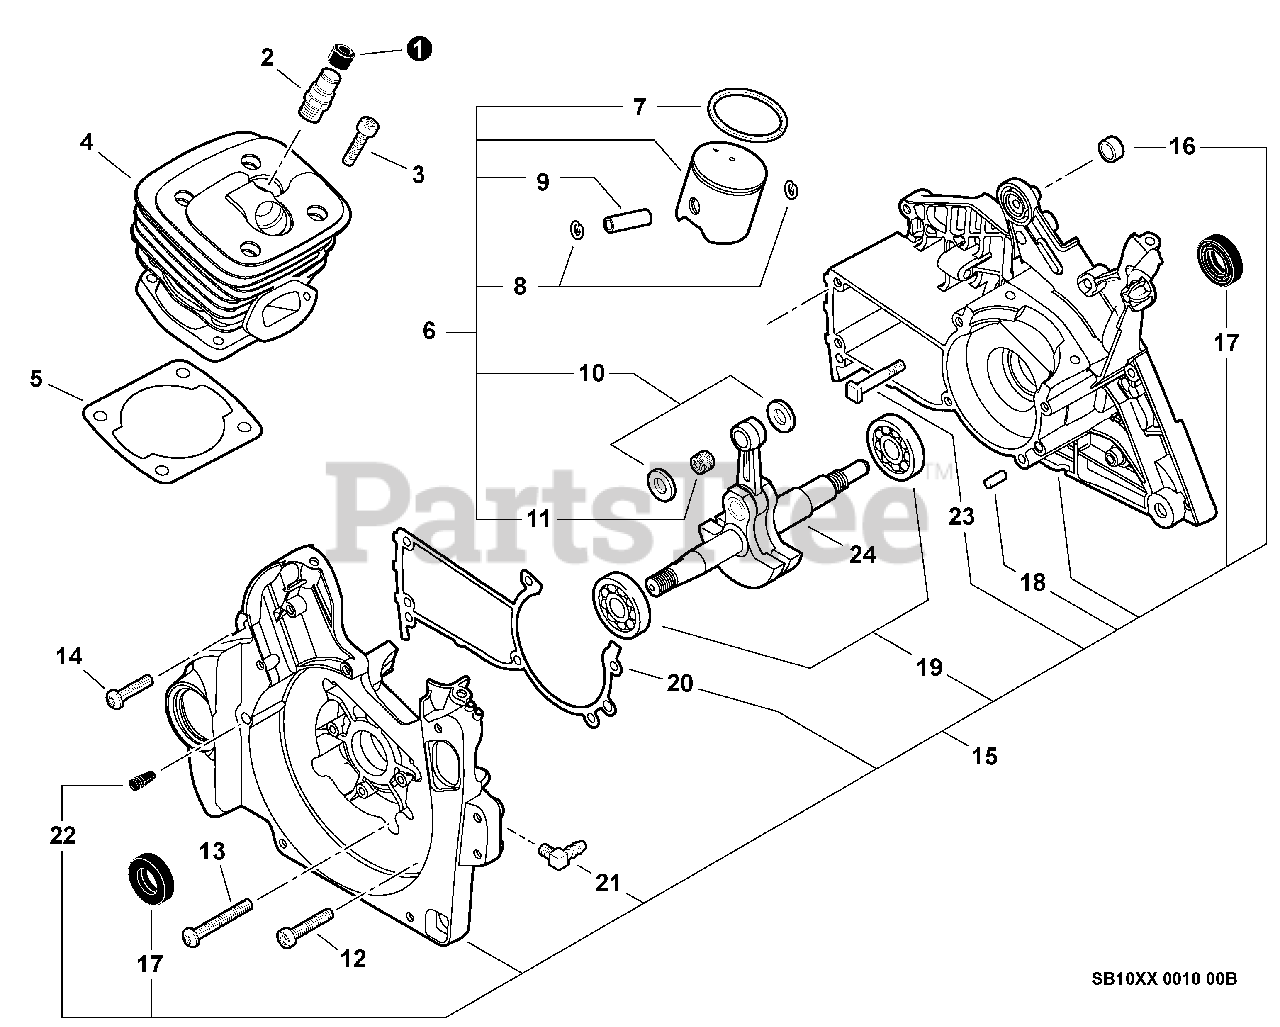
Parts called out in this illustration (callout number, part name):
1	COVER, DUST
2	VALVE ASSY, DECOMPRESSION
3	BOLT, TORX 5×25
4	CYLINDER
5	GASKET, CYLINDER
6	PISTON KIT
7	RING, PISTON
8	RING, SNAP Ø11
9	PIN, PISTON
10	WASHER, THRUST
11	BEARING, NEEDLE 11
12	BOLT, TORX 5×25
13	BOLT, TORX 5×35
14	BOLT, TORX 5×20
15	CRANKCASE KIT
16	SPACER 12×10×T: 1.0
17	SEAL, OIL 15
18	PIN, LOCATING 5×10
19	BEARING, BALL 6202
20	GASKET, CRANKCASE
21	CONNECTOR, PIPE
22	VENT ASSY
23	BOLT, STUD M8×1.25×34.5
24	CRANKSHAFT ASSY
